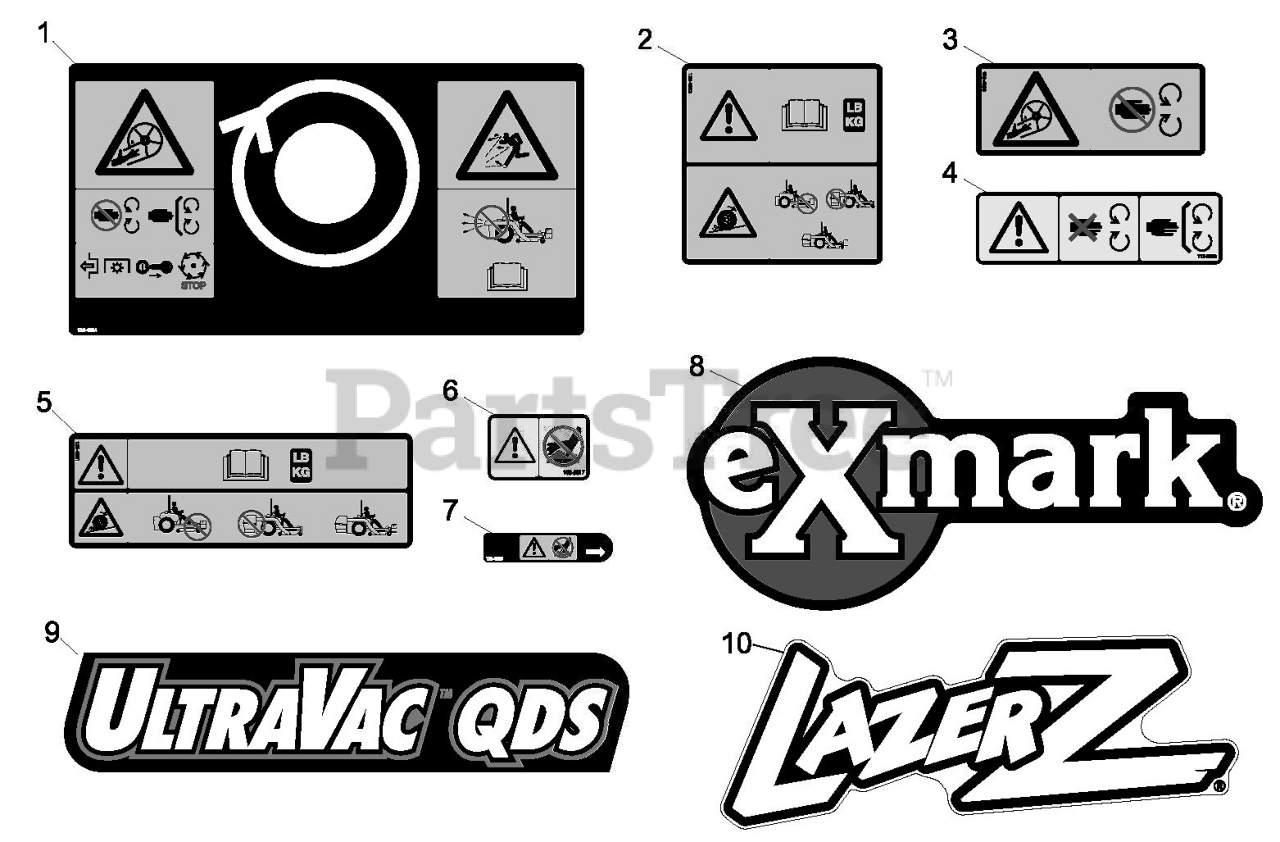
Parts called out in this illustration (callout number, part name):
1	Decal-Warning Blower
2	DECAL-WARNING, TRACTION
3	Decal-Blower Impeller Hazard
4	DECAL-COVER, MISSING
5	DECAL-WARNING WEIGHT
6	DECAL-WARNING
7	DECAL-WARNING
8	DECAL, EXMARK
9	DECAL, ULTRAVAC QDS
10	DECAL,LAZER MODEL
